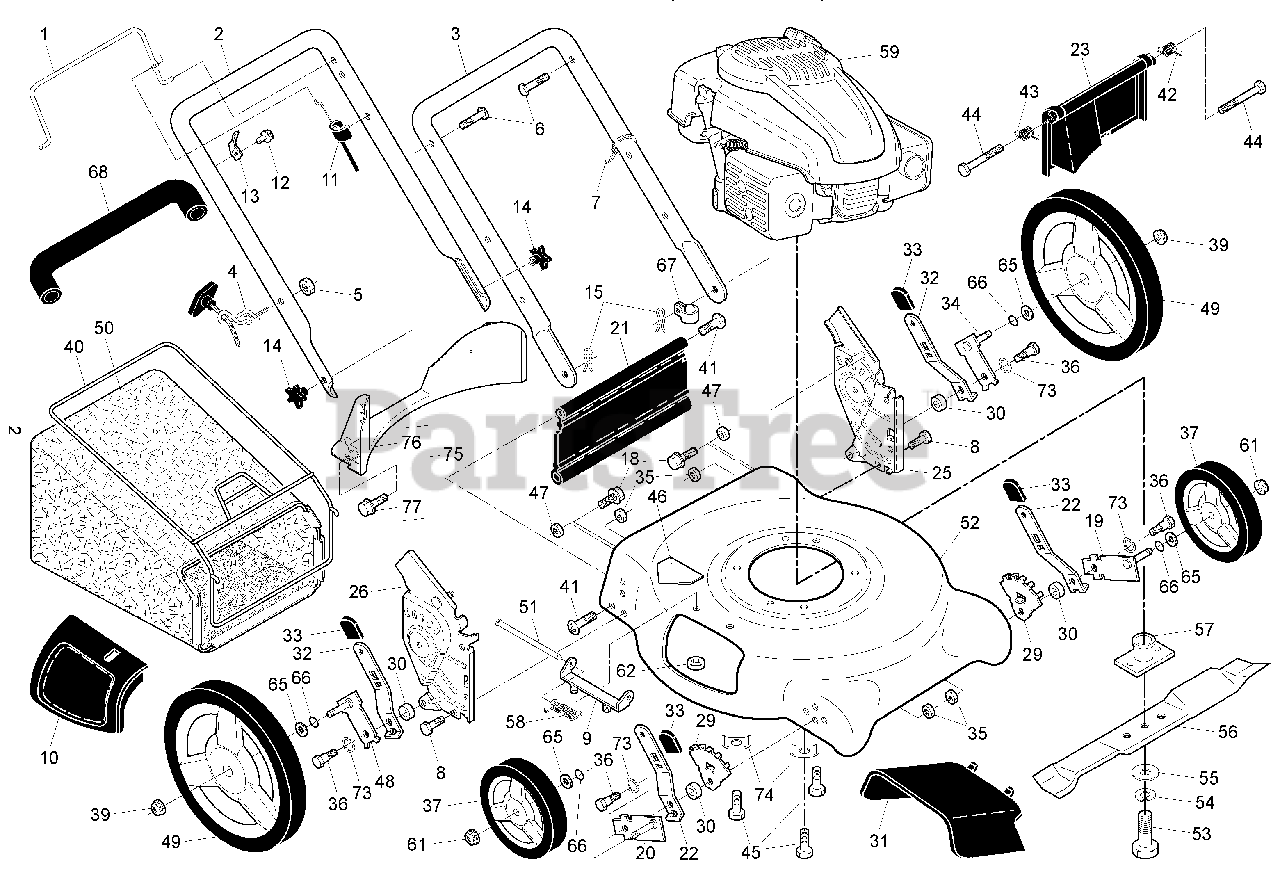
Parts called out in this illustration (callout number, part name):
1	Control Bar
2	Upper Handle
3	Lower Handle
4	Rope Guide
5	Locknut, Hex 1/4-20
6	Handle Bolt
7	Wire Tie
8	Hex Bolt 5/16-18 x 3/4
9	Hinge Bracket Assembly
10	Mulcher Door
11	Engine Zone Control Cable
12	Hex Washer Head Screw #10-24 x 1/2
13	Up-Stop Bracket
14	Handle Knob
15	Hairpin Cotter
18	Screw 1/4-20 x 3/8
19	Axle Arm Assembly, Front, LH
20	Axle Arm Assembly, Front, RH
21	Kit, Rear Skirt
22	Selector Spring, Front
23	Rear Door Assembly
25	Handle Bracket Assembly, LH
26	Handle Bracket Assembly, RH
29	Wheel Adjusting Bracket, Front
31	Discharge Deflector
32	Selector Spring, Rear
33	Selector Knob
34	Axle Arm Assembly, Rear, LH
35	Nut, Hex
36	Shoulder Bolt 5/16-18
37	Wheel & Tire Assembly, Front 8 x 1-3/4
39	Nut, Hex, Flangelock
40	Frame, Grassbag
41	Hinge Screw
42	Spring, Rear Door, LH
43	Spring, Rear Door, RH
44	Bolt, Rear Door
45	Hex Head Thread Rolling Screw 3/8-16 x 1
46	Danger Decal
47	Locknut, Hex 5/16-18
48	Axle Arm Assembly, Rear, RH
49	Wheel & Tire Assembly, Rear 12 x 1-3/4
50	Grassbag
52	Kit, Lawn Mower Housing Assembly
53	Hex Head Screw 3/8-24 x 1-3/8 Grade 8
54	Helical Lockwasher
55	Hardened Washer
56	21" Blade
57	Blade Adapter
58	Spring, Torsion
61	Nut, Hex, Flangelock
62	Nut, Hex, Nylock 1/4-20
65	Washer, Flat
67	Clip, Cable
68	Grip, Foam
73	Washer, Flat
74	Washer, Special, Engine, Zinc-Plated
75	Kit, Rear Baffle
76	Baffle, Rear
77	Screw, Rear Baffle
